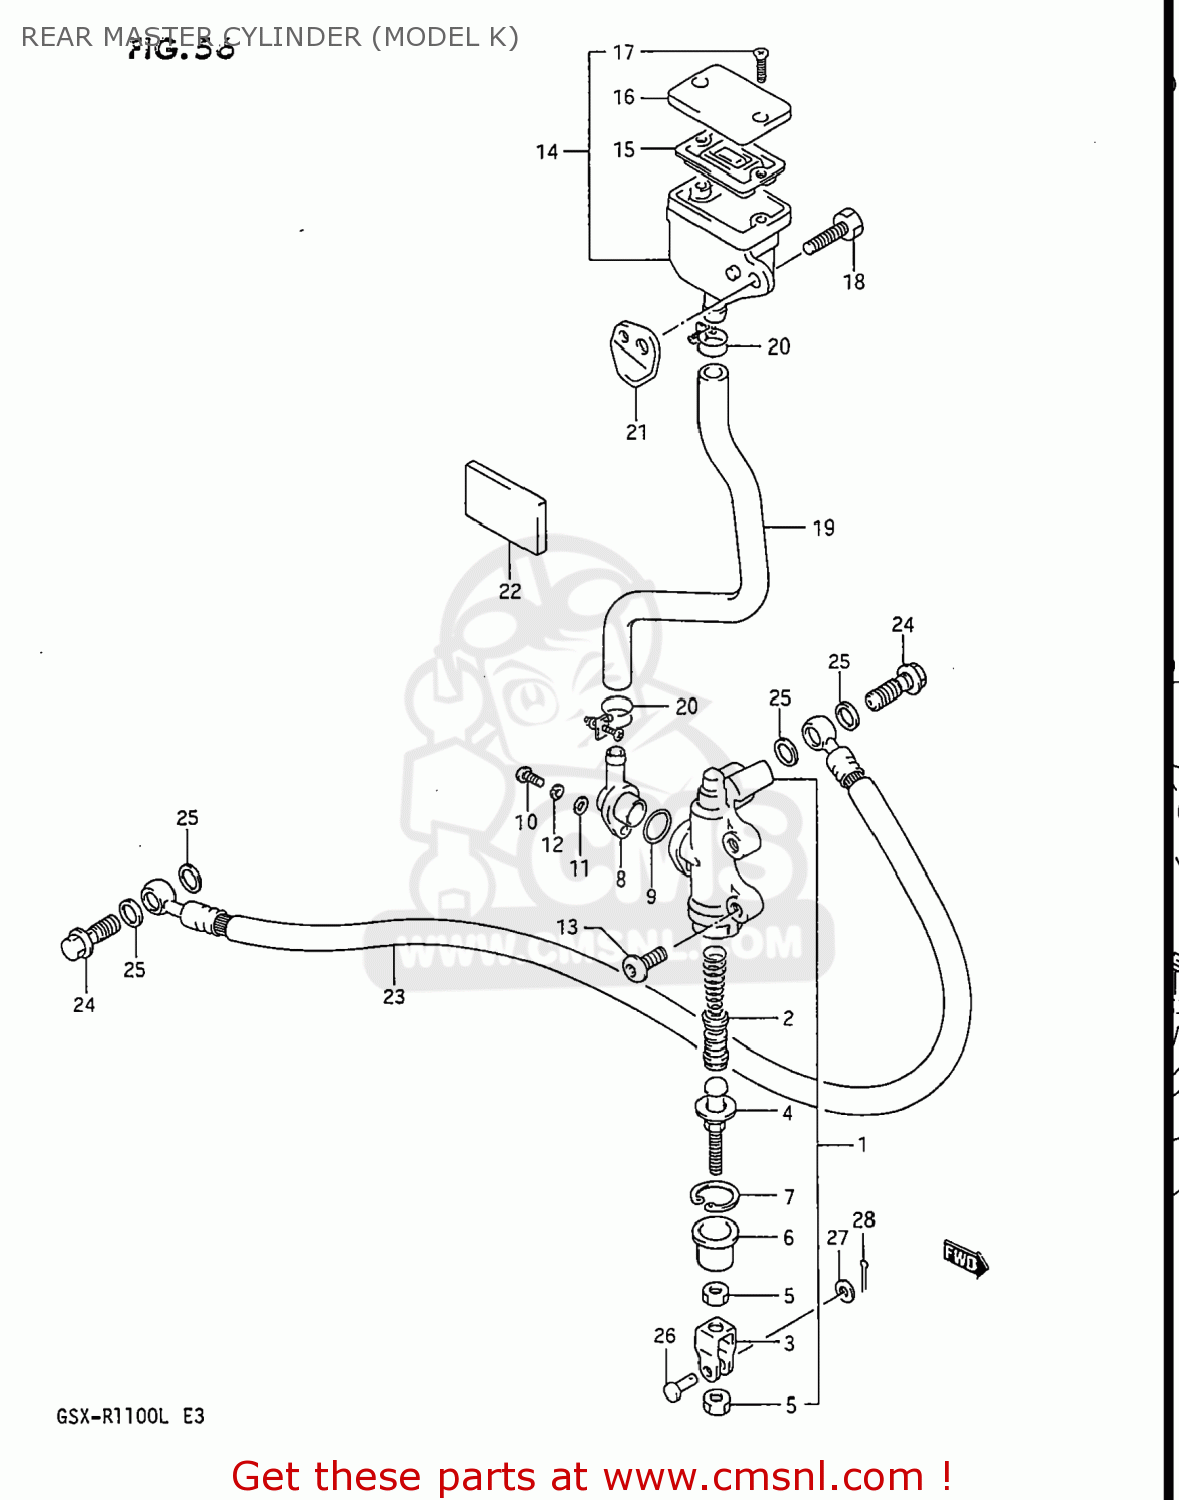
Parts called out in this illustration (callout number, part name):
1	CYLINDER ASSEMBLY,REAR MASTER
2	PISTON/CUP SET
3	YOKE
4	ROD,PUSH
5	NUT
6	BOOT
7	CIRCLIP
8	CONNECTOR
9	O RING
10	SCREW
11	WASHER
12	LOCK WASHER
13	SCREW(8X22)
14	TANK ASSEMBLY,RESERVOIR
15	DIAPHRAGM
16	CAP
17	SCREW
18	BOLT
19	HOSE,RESERVOIR TANK
20	CLAMP
21	BRACKET,RESERVOIR TANK RR
22	CUSHION,PANEL
23	HOSE COMP,REAR BRAKE
24	BOLT UNION
25	WASHER(10X15X1.5)
26	PIN
27	WASHER
28	PIN
